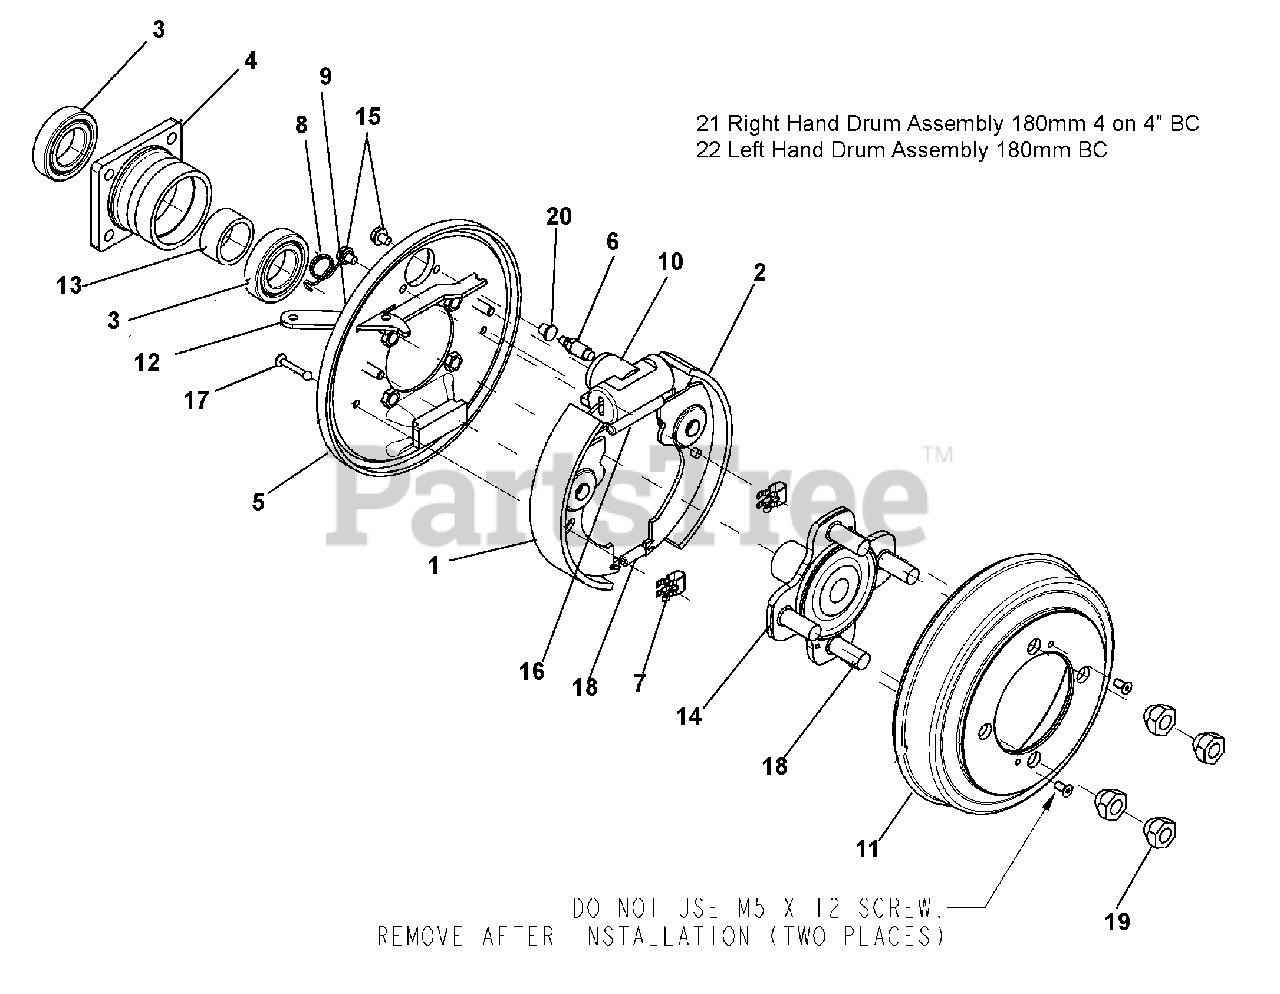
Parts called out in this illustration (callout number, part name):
1	CMX LEFT SHOE
2	CMX RIGHT SHOE
3	CMX BALL BEARING
4	CMX BEARING HOLDER HUB
5	CMX BRAKE SHOE DISC RH
5	CMX BRAKE SHOE DISC LH
6	CMEX BLEEDER SCREW
7	CMX SHOES LOCKING SPRING
8	CMX RIGHT SPRING/HAND BRAKE LV
9	CMX LEFT SPRING/HAND BRAKE LV
10	CMX HYDRAULIC CYLINDER
11	CMX DRUM
12	CMX RIGHT LEVERS SET
12	CMX LEFT LEVERS SET
13	CMX SPACER
14	BRAKE FLANGE HUB W/STUDS
15	CMX SCREW M6X40
16	CMX UPPER RETURN SPRING
17	CMX SPRING PIN
18	CMX LOWER RETURN SPRING
19	NUT, 1/2-20 LUG, GRADE 5
20	BLEEDER CAP
21	RH DRUM ASM 180MM 4 ON 4" BC
22	LH DRUM ASM 180MM 4 ON 4" BC
